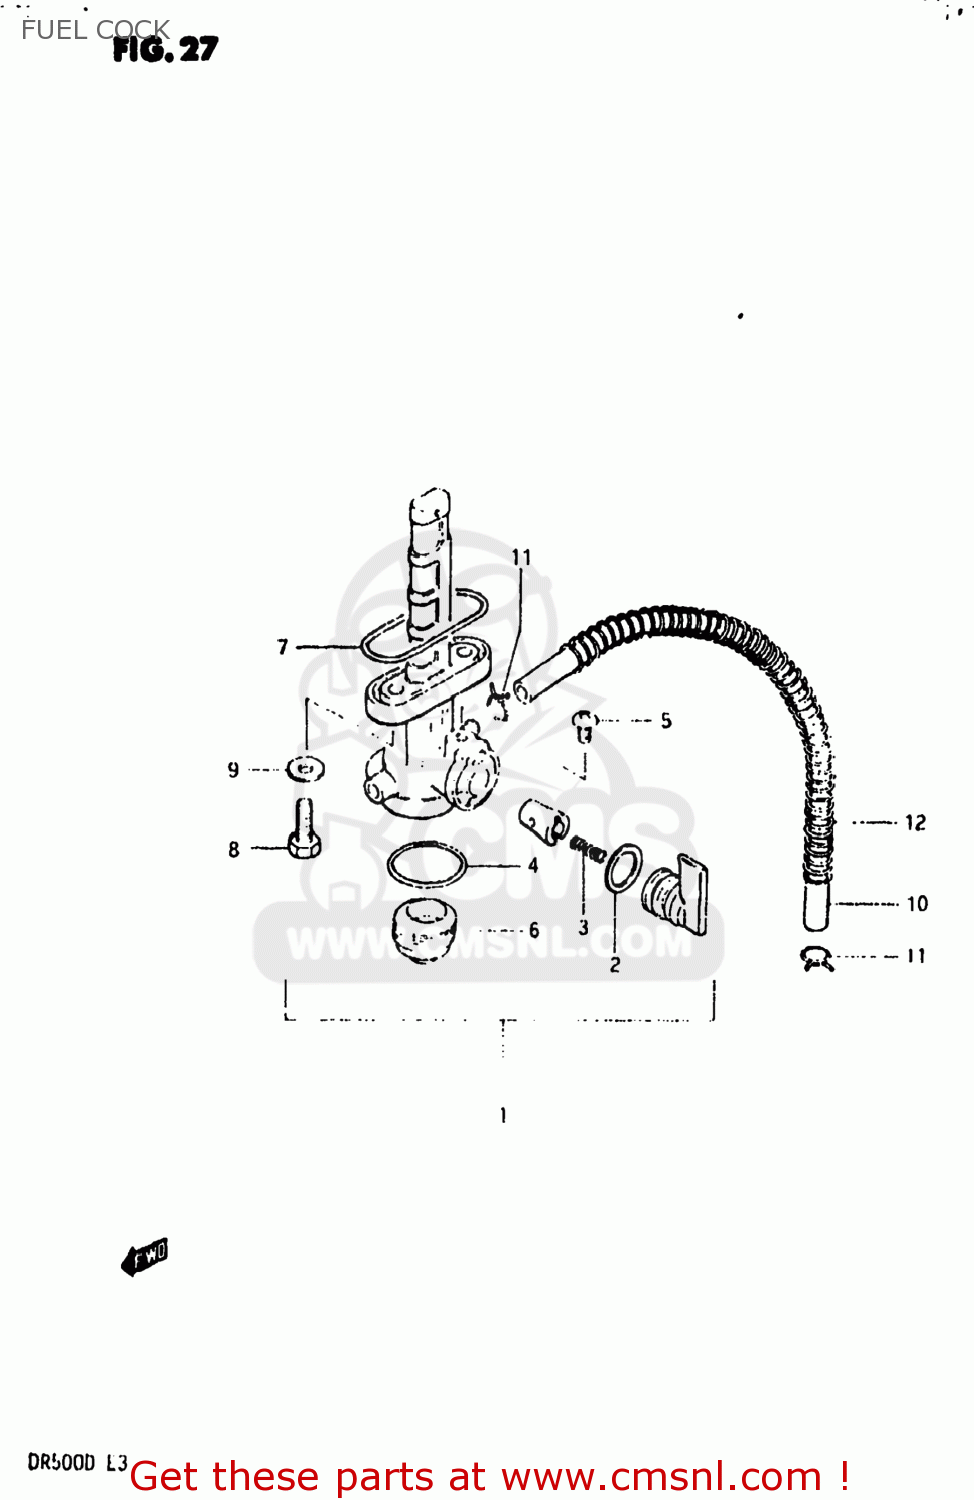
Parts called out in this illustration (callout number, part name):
1	COCK ASSEMBLY,FUEL
2	O-RING
3	SPRING
4	GASKET,FILTER (NAS)
5	SCREW,FUEL COCK LEVER
6	CUP,STRAINER
7	O RING,FUEL COCK
8	BOLT(6X20)
9	GASKET
10	HOSE
11	CLIP
12	SPRING
